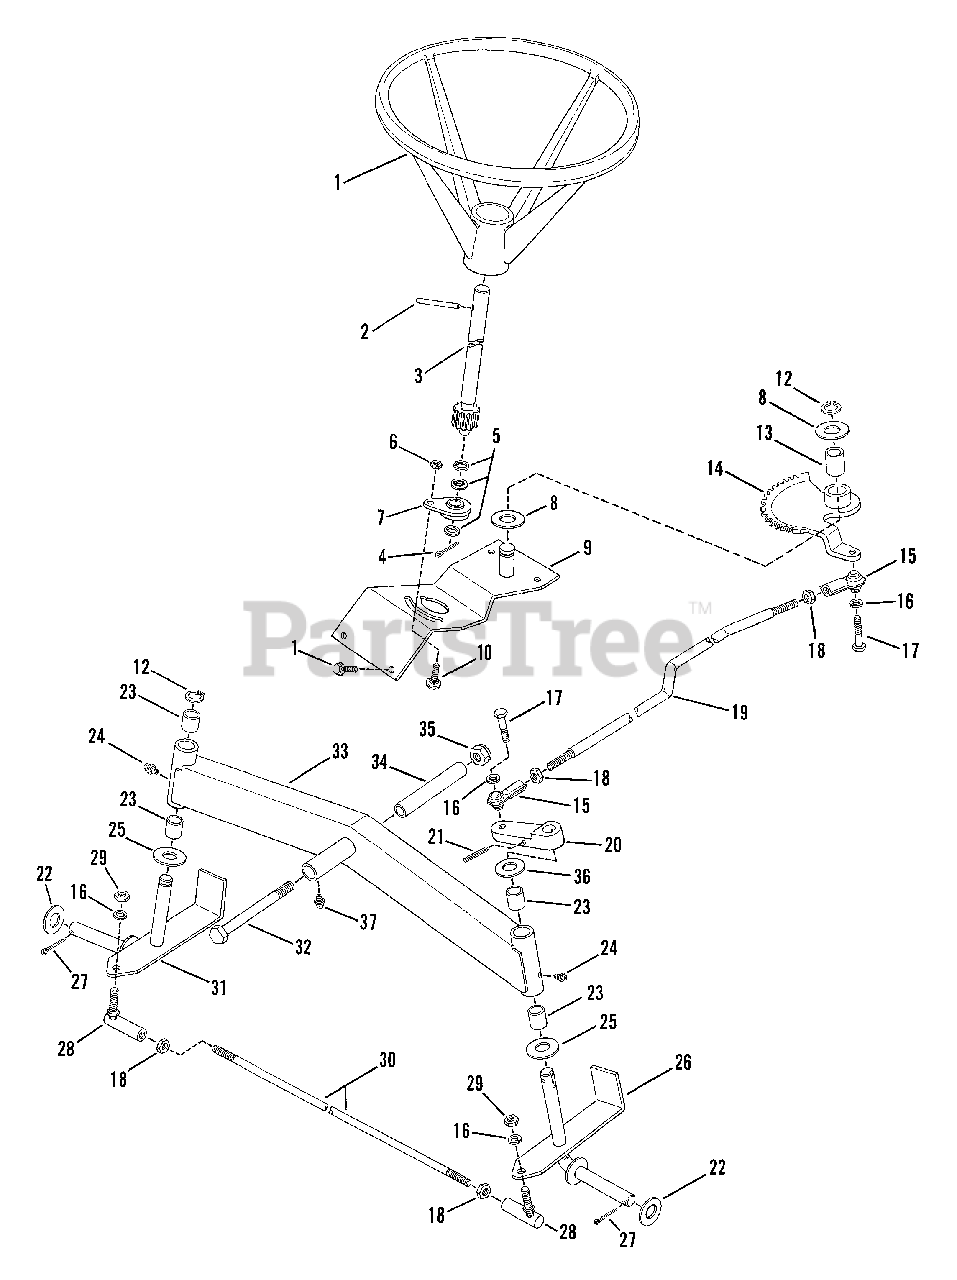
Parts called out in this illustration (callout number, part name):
1	STEERING WHEEL
2	ROLL-PIN
3	SHAFT, Steering
4	PIN, Cotter 3/23X1.0
5	WASHER, Shim
6	LOCKNUT, 1/4-20 Hex Flange
7	ADJUSTER, Steering
8	WASHER, Thrust
9	ASSEMBLY, Steering Support
10	BOLT, 1/4-20x5/8" Short Neck Carriage
11	SCREW, 5/16-18x5/8" Self-Tapping
12	RING, Retaining
13	BEARING
14	ASSEMBLY, Sector
15	BALL JOINT, Drag Link 3/8-24
16	LOCKWASHER, 3/8 Split
17	SCREW, 3/8-24x1-1/4" Hex Head Cap
18	JAM-NUT, 3/8-24 Hex
19	DRAG-LINK
20	ARM, Steering
21	ROLL-PIN
22	WASHER, Flat
23	BEARING, Sleeve
24	LUBE FITTING, Straight (press-fit for .187 dia. Hole)
25	WASHER, Thrust
26	SPINDLE ASSEMBLY, L.H.
27	COTTER-PIN
28	BALL JOINT, 3/8-24 Thread
29	NUT, 3/8-24 Hex
30	TIE-ROD
31	SPINDLE ASSEMBLY, R.H.
32	SCREW, 1/2-20x4-1/2" Hex Head Cap
33	ASSEMBLY, Front Axle
34	SPACER, Axle Pivot
35	LOCKNUT,1/2-20 Hex
36	WASHER
37	FITTING, Lube
